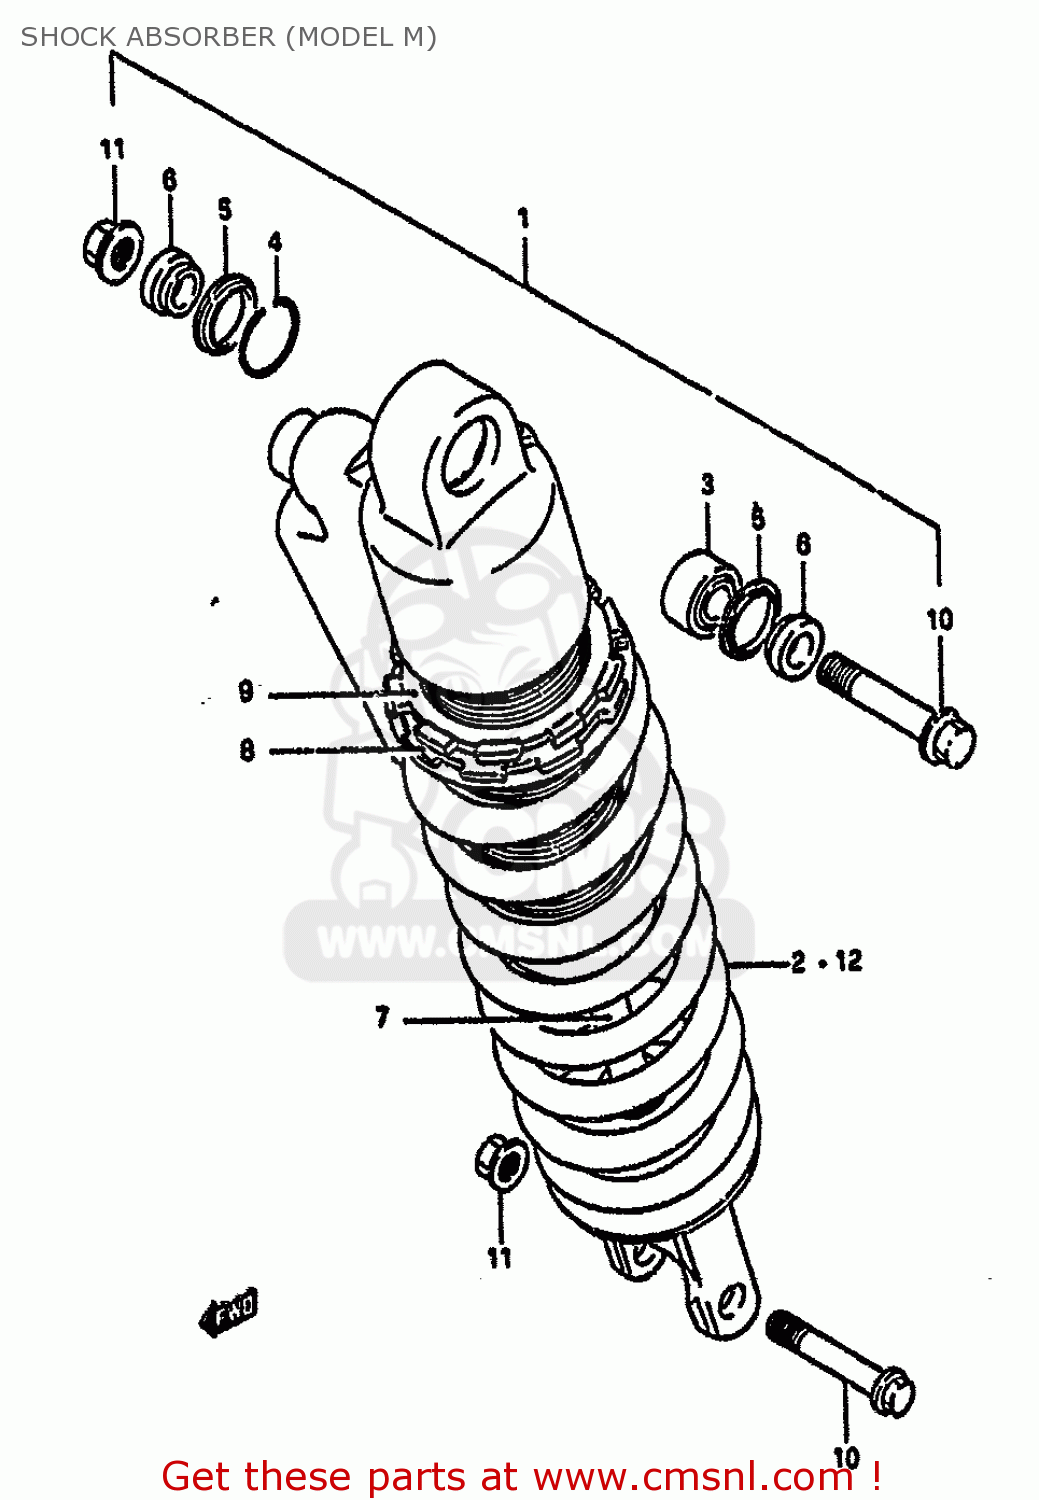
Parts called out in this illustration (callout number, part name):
1	ABSORBER ASSEMBLY,REAR SHOCK
2	SPRING
3	BEARING,REAR SHOCK ABSORBER
4	RING,STOPPER
5	SEAL,DUST
6	COLLAR
7	ROD,PISTON
8	GUIDE,SPRING
9	NUT
10	BOLT,REAR SHOCK ABSORBER
11	NUT
12	SPRING
